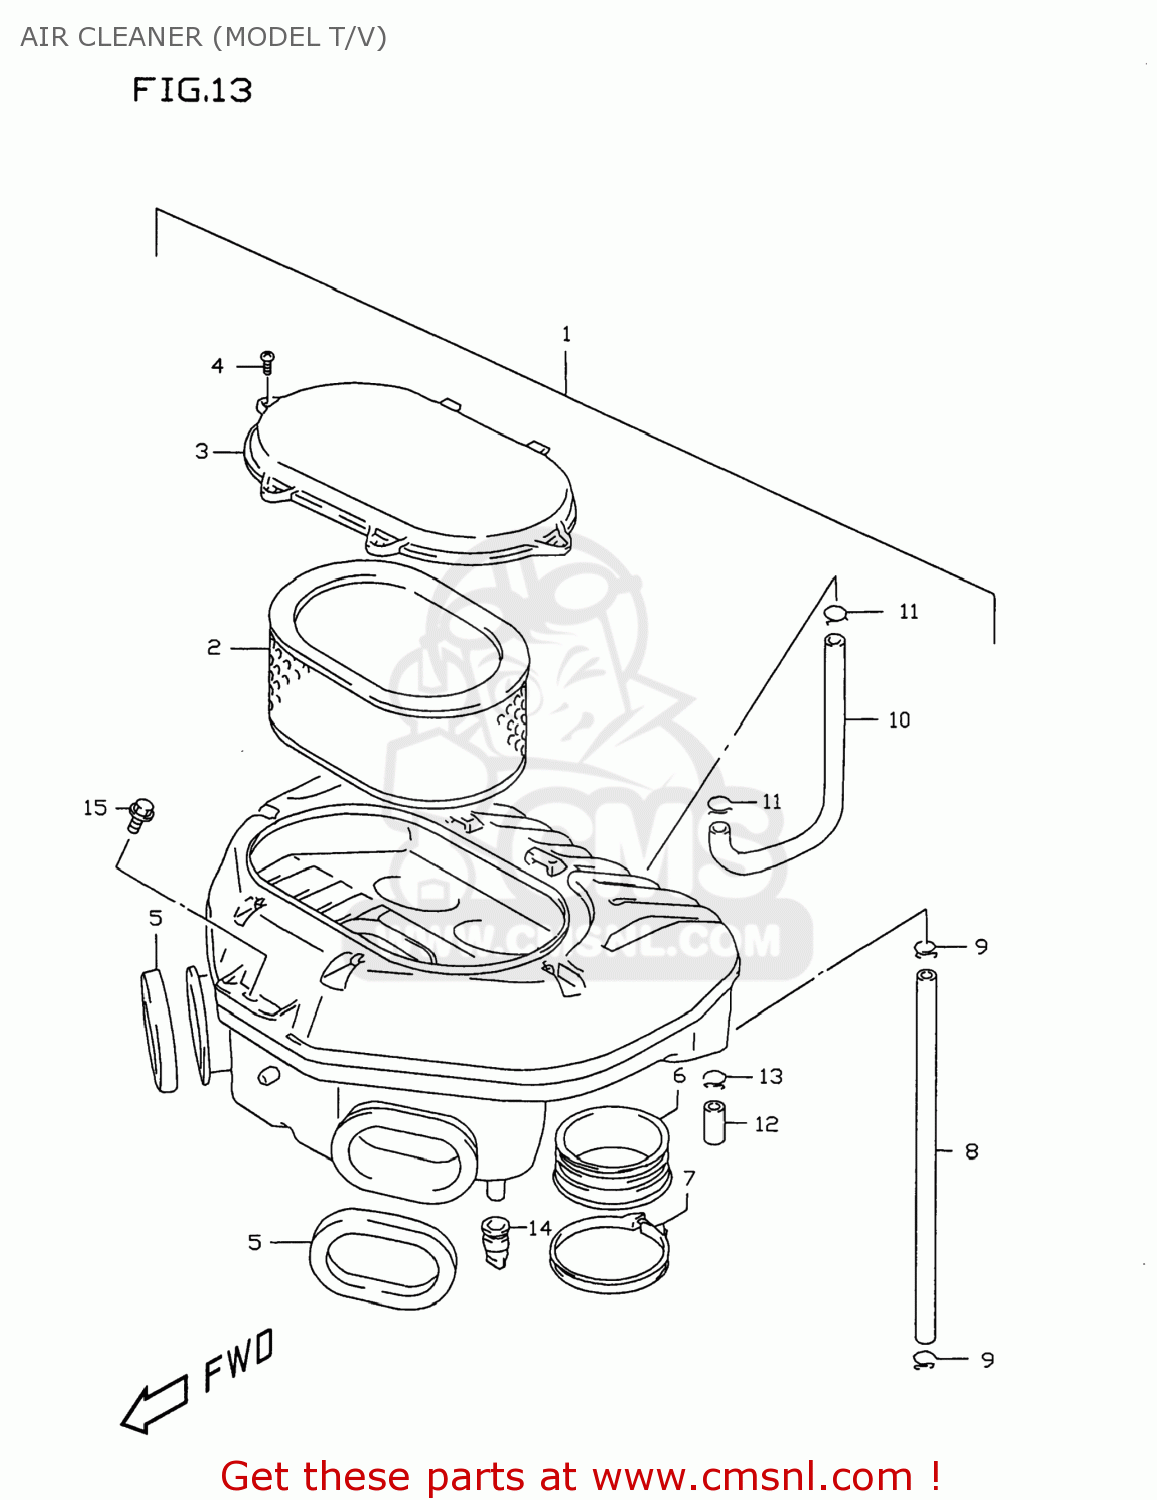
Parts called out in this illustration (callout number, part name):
1	CLEANER ASSY,AIR
2	FILTER,AIR CLEANER
3	CAP,AIR CLEANER
4	SCREW 5X12
5	CUSHION,DUCT
6	TUBE,OUTLET
7	CLAMP
8	TUBE,BREATHER
9	CLIP
10	TUBE,CONTROL AIR
11	CLIP
12	PLUG
13	CLIP
14	CAP,DRAIN
15	BOLT
